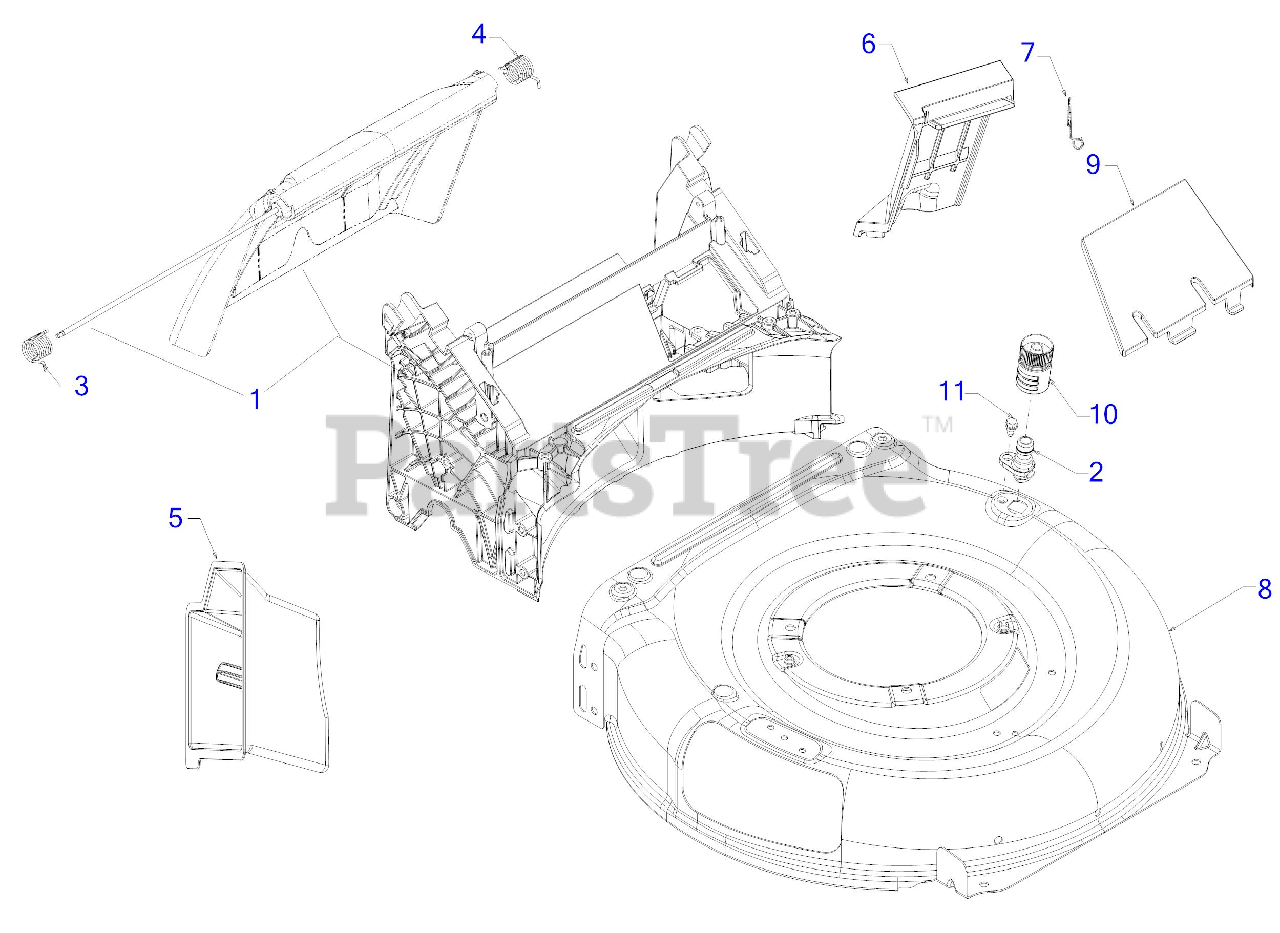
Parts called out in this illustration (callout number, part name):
1	REAR BAFFLE ASSEMBLY
2	DECK WASH NOZZLE
3	TORSION SPRING (RH)
4	TORSION SPRING (LH)
5	MULCH PLUG
6	TRANSMISSION COVER (FRONT)
7	CABLE CLIP
9	TRANSMISSION COVER (REAR)
10	WATER NOZZLE
11	SHOULDER SCREW 1/4-20 x .50
